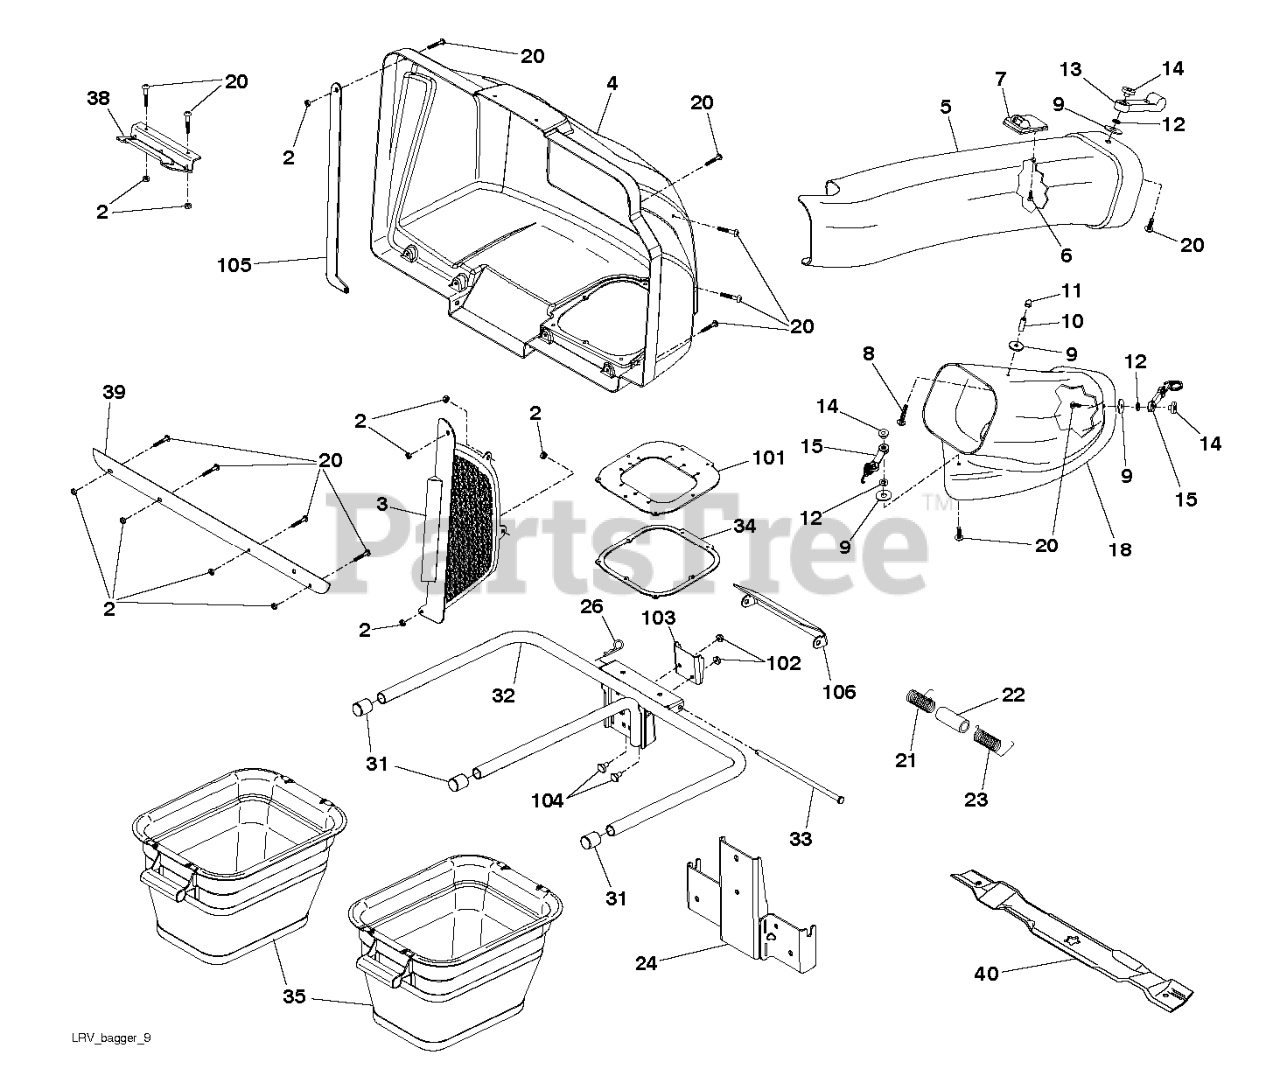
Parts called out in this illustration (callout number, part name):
4	COVER.TOP.GENERIC.
5	CHUTE.UPPER.LTVB.30".BAGGER
6	SCREW.#10 X 0.750.BOS
7	INDICATOR ASM BAG
8	SCREW
9	RP STEEL WASHER
11	NUT
12	LOCKWASHER #10
13	LATCH.HOOD.
14	WELDNUT
15	LATCH ASSY
18	CHUTE.LOWER.30" LRV(B)
20	SCREW
21	SPRING COVER LH
22	SPACER.COVER.BAGGER
23	SPRING COVER RH
24	SUPPORT.ASM.BAGGER
26	RETAINER-SPRNG RB
31	PLUG, TUBING END
32	FRAME ASSEMBLY, 2 BIN
33	BAGGER.HINGE.PIN
34	RING.SEAL.BAGGER.PNT
35	SOFT.BAG.ASSEM.G30LRV
38	LATCH CER38
39	STRIP.REINFORCE.BAGGER.2BIN.BL
40	BLADE.MOWER.BAGGING.30"
101	GASKET.COVER.BAGGER.
102	NUT LOCK HEX FLANGE 5/16-18
105	SEAL.SIDE.LRV.L
